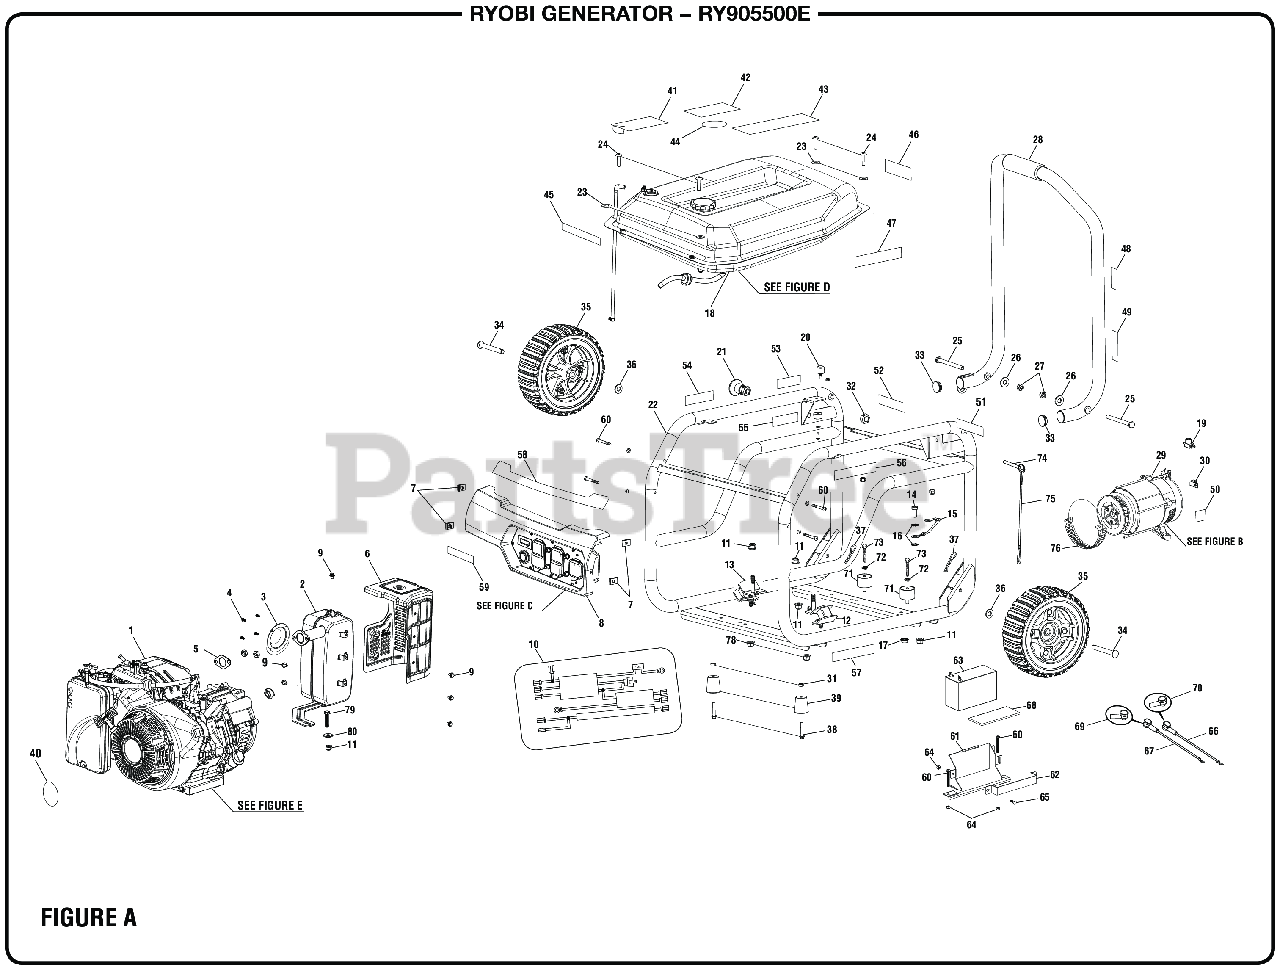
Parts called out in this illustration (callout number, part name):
3	Spark Arrester Screen
4	Screw (8-32 x 3/8 in., Pan Hd.)
5	Exhaust Gasket
6	Heat Shield
7	U-Clip (M6)
8	Control Panel Assembly
9	Bolt (M6 x 9 mm, Hex Flange Hd.)
10	Wire Assembly
11	Lock Nut (M8 x 1.25 mm, Flange)
12	Engine Isolator (Large)
13	Engine Isolator (Right)
14	Bolt (5/16-18 x 3/4 in., Hex. Hd.)
15	Assembly, ground wire
16	Washer (5/16 in., External Star)
17	Flange Nut (5/16-18, Hex Hd.)
18	Fuel System
19	Rubber Sleeve
20	Rubber Bumper
21	Quick Release Pin Assembly
22	Carrier Assembly
23	Washer (1/4 in., Type A)
24	Screw (1/4-20 x 1 in., T30 Torx Hd.)
25	Handle Pivot Pin (5/6-18 x 90 mm)
26	Washer ( 5/16 in.)
27	Lock Nut (5/16-18, Hex Hd.)
28	Handle Assembly
29	Generator Head Assembly (See Fig. A)
30	Ground Lug (5/16-24) (BM903600)
31	Lock Nut (M8 x 1.25)
32	Lock Nut (1/2-20, Hex)
34	Washer (M10)
35	Handle Isolator
36	Washer (OD19.75 x ID10.5 x 1t)
37	Hitch Pin (M3)
38	Bolt (M8 x 1.25 in., Flange Hex Hd.)
39	Foot Assembly
40	Engine Recoil Label
41	Warning Hangtag
42	Warning Label
43	CPSC (English) Label
44	Remove Cap Fuel Stabilizer Label (English)
45	Logo Label
46	UL Fire Warning Label Spark Arrestor)
47	Start Label
48	Fuel Stabilizer Label (French/Spanish)
49	No E85 Label
50	Ground Label Icon
51	Ground Warning Label
52	Risk of Fire Danger Label
53	Quick Release Pin Label
54	Inquires Label (Ryobi)
56	Fire Distance Label (Eng/Sp)
57	Engine Lubricant Label
58	Performance Label
59	Choke Label
60	Screw (M6 x 50 mm, T30 Torx Pan Hd. )
61	Battery Box Gasket
62	Battery Hold Down Bracket Assembly
63	Battery Bracket
64	Lock Nut (M6 x 1 mm)
65	Screw (M6 x 16 mm, Hex Hd.)
66	Battery Cable (Red)
67	Battery Cable (Black)
68	Gasket (Battery Hold Down Bracket)
69	Rubber Battery Cable Boot (Black)
70	Rubber Battery Cable Boot (Red)
71	Isolator Generation 7
72	Lock Washer (OD14.8 x ID8.5 x 1t)
73	Bolt (M8 x 1.25 in., Hex Hd.)
74	Release Pin (5/16 x 2 in.)
75	Lanyard (3/16 in.)
76	Fan Cover (Generator Head)
78	Lock Nut (5/16-18)
79	Screw (M8 x 40 mm, Hex Hd.)
80	Washer (ID9 x OD25.4 x 2t)
